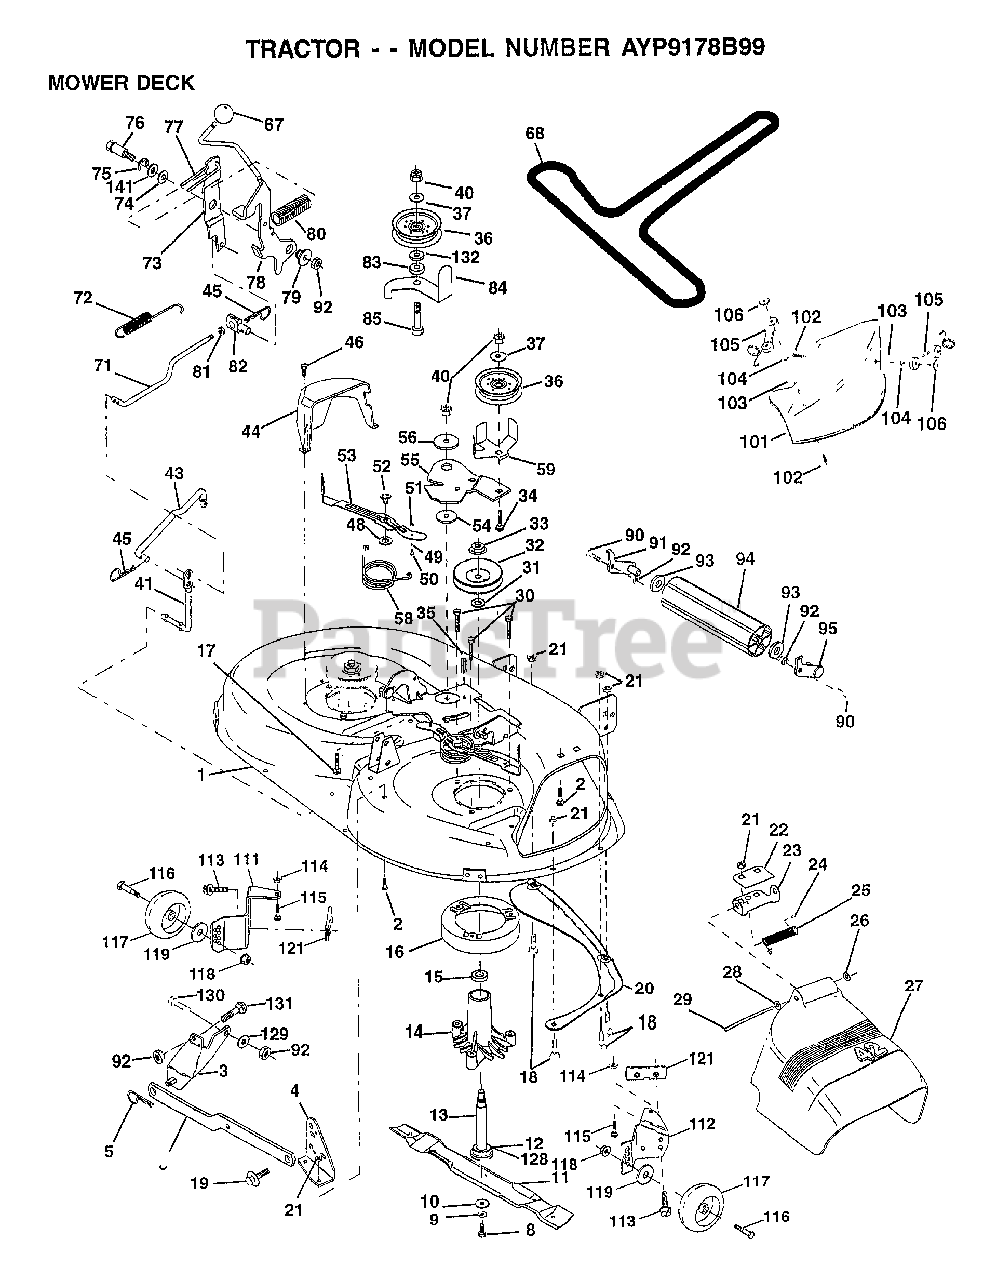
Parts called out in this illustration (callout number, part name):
1	"HOUSING ASSY.42"""
2	BOLT
3	BRKT ASM SWAY BAR
4	BRKT DECK SW BAR
8	BLADE BOLT
10	WASHER.HARD.BLADE
11	"BLADE.42"" MULCHER"
12	BEARING.BALL
14	HSG ASM MANDREL
15	BEARING
16	STRIPPER RND MWR
17	BOLT RDHD 3/8-16
18	BOLT
19	BOLT SHD 5/16-18
20	BAFFLE VORTEX 42
22	STIFFENER BRKT
23	DEFLECTOR BRKT
24	CAP-SLEEVE LT
25	SPRING TORSION
26	NUT PUSH M
27	DEFLECTOR.SHIELD
28	WASHER
29	HINGE ROD
30	"SCREW-THD ROLL,WA"
31	WASHER
32	PULLEY.MANDREL.42
34	BOLT
35	XMAS TREE FASTNER
36	FLAT IDLER PULLEY
37	WASHER
41	PIVOT ROD
43	ROD CLUTCH W/NIBS
44	GUARD MAND LH BLK
45	RETAINER M
46	SCREW.1/4-20X5/8
48	HARD SMALL WASHER
49	ROLLER ASM-CAM
50	SHOULDER BOLT
51	LOCKNUT
52	BOLT.SHLD.5/16-18
53	BRAKE PAD ARM ASM
54	HARDENED WASHER
55	ARM-IDLER
56	SPACER RETAINER
58	SPRING TORSN BRAK
59	GUARD IDLER TUV
67	KNOB.RD.7/16-14
68	BELT.V.T-PATH
71	ROD CLUTCH 38/42
72	RETURN SPRING
73	CLUTCH ARM SECOND
74	WASHER
75	RING
76	SHOULDER BOLT
77	SPRING KEEPER
78	LEVER.ASM.CLUTCH
79	BUSHING
80	SPRING.CLUTCH.MWR
81	NUT
82	TRUNION ADJ
83	WASHER
84	"KEEPER-BELT,FIXED"
85	BOLT
90	BOLT
92	NUT
93	WASHER
101	"COVER.MULCH.42"""
102	SCREW
103	WASHER #10
104	LOCKWASHER
105	LATCH ASSY.BAGGER
106	WELDNUT
111	BRACKET.GWHL.LH.
112	BRACKET.GWHL.RH.
113	SCREW
116	BOLT.SHOULDER
117	WHEEL GAGE DONUT
118	LOCKNUT
119	WASHER
121	BRACKET.EXTRD.GWL
128	WASHER.FELT.
129	WASHER
130	BOLT
132	WASHER GT
141	WASHER .T
